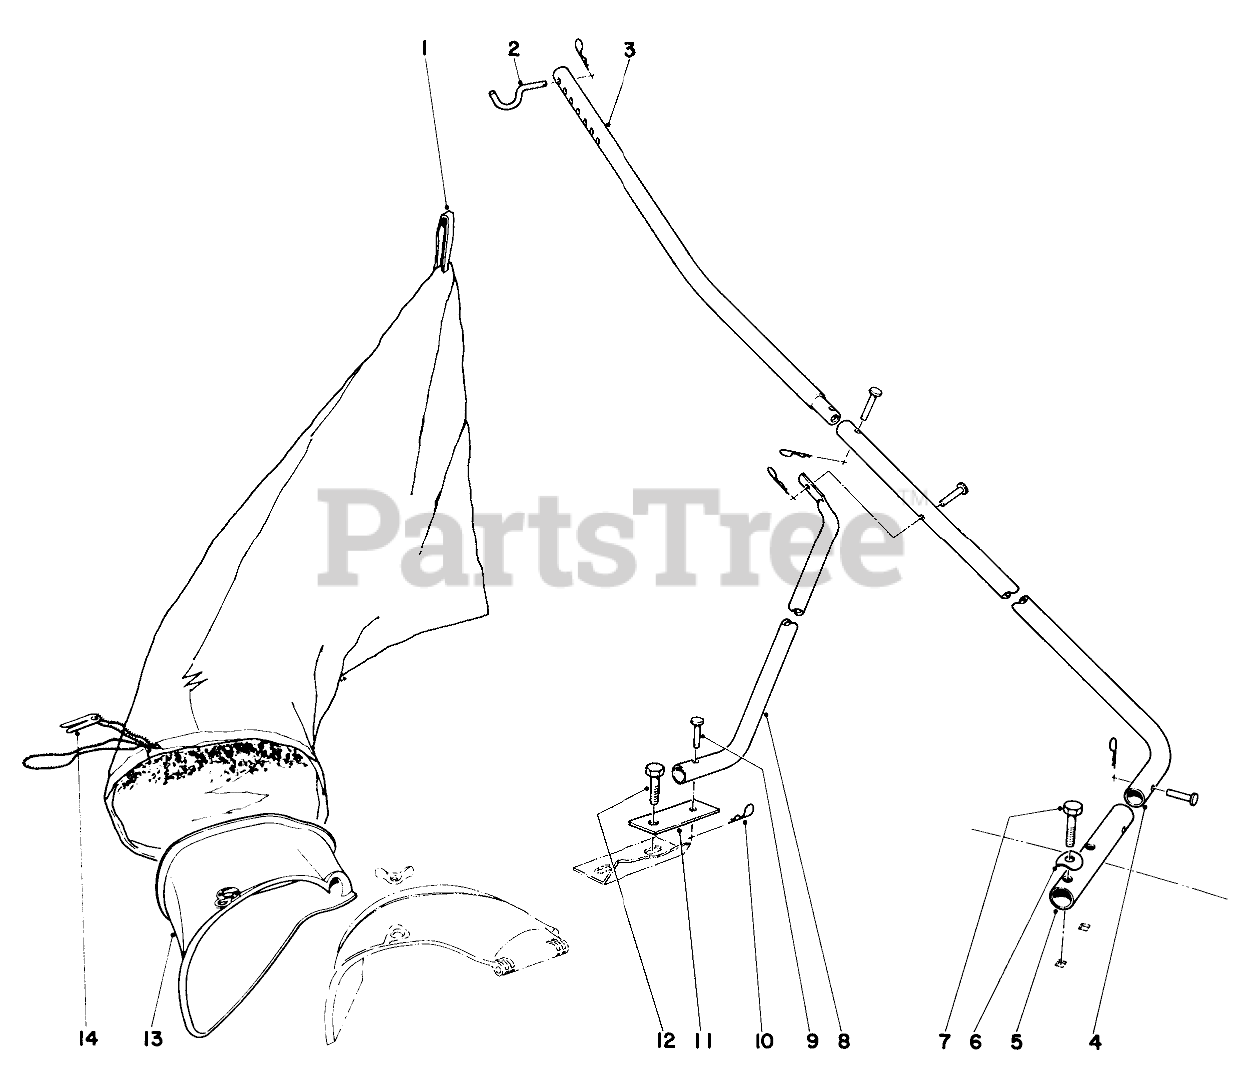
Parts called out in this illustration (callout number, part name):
1	Bag Assembly
3	Arm Shaft
5	Socket-Bag Arm
6	Curved Washer
7	SCREW-HH
8	Brace
10	PIN-COTTER, HAIR
11	Brace Support
12	SCREW-HH
13	Bag Attachment
14	BAG CORD FASTENER
